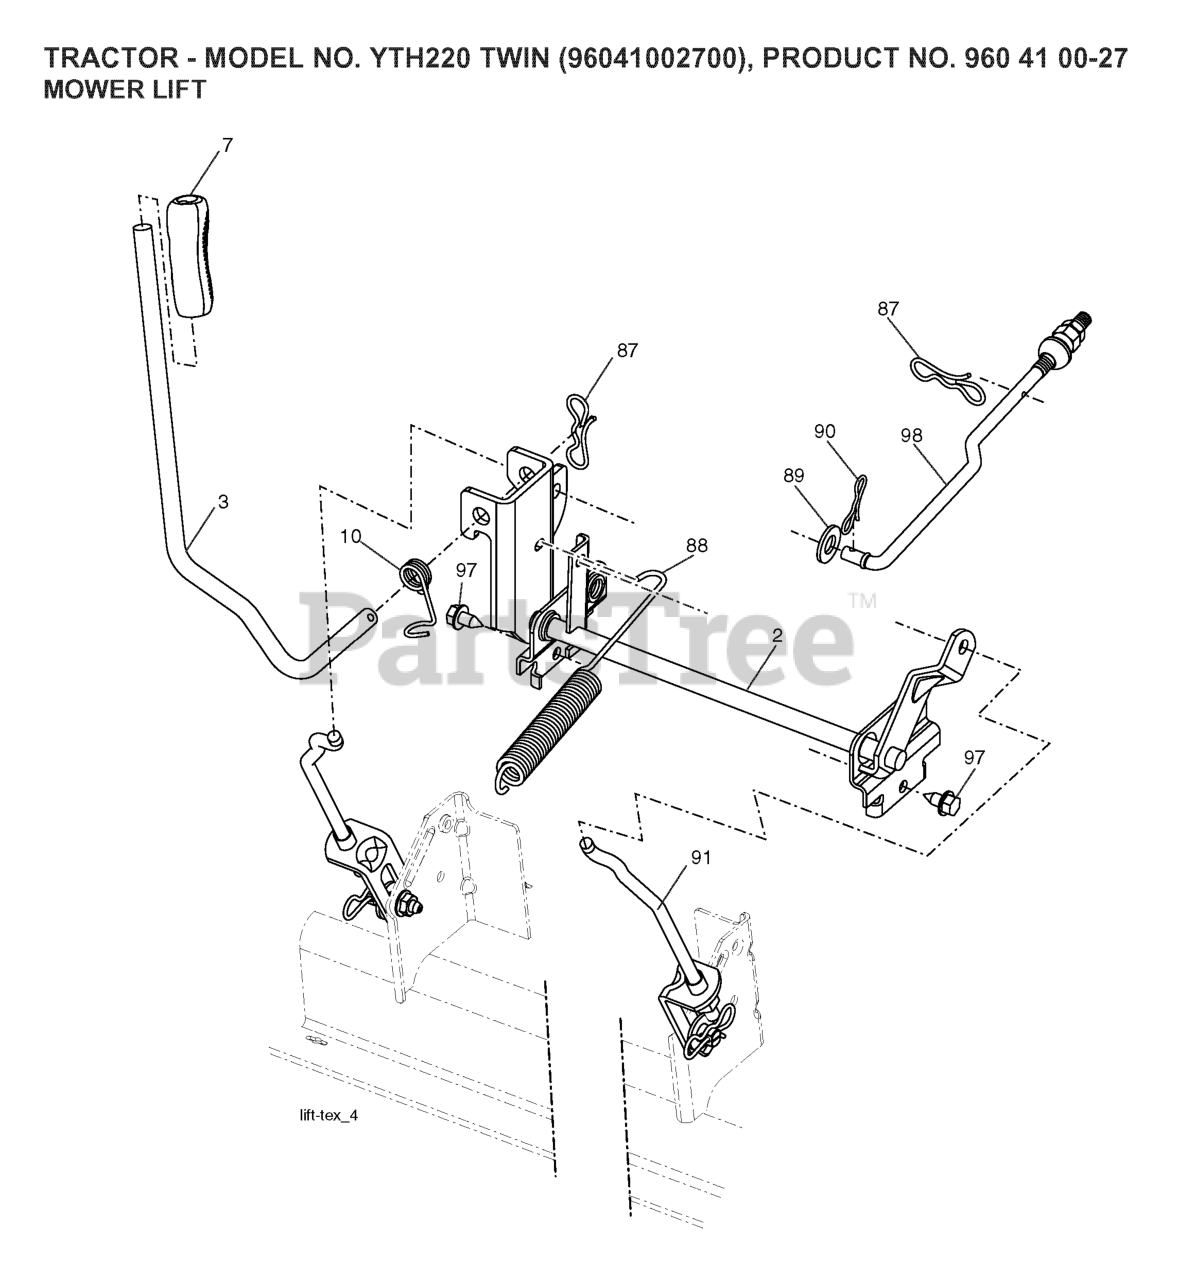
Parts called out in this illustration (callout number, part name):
2	SHAFT.ASM.LIFT.CROSS.H
3	LEVER.LIFT.HANDLE.GT
7	GRIP.HANDLE.LIFT.PVC.BLACK
10	SPRING.TORSION.LIFT.HANDLE
87	PIN.COTTER.7/16.BOW TI.
88	SPRING.LIFT.ASSIST.GT2
89	WASHER.CLEAR.ZINC
90	PIN.COTTER.5/16.BOW TI
91	LINK.LIFT.ASM.REAR.GT.
97	SCREW 3/8-16X3/4
98	LINK.ASM.SUSP.FRONT.MWR.10.5
